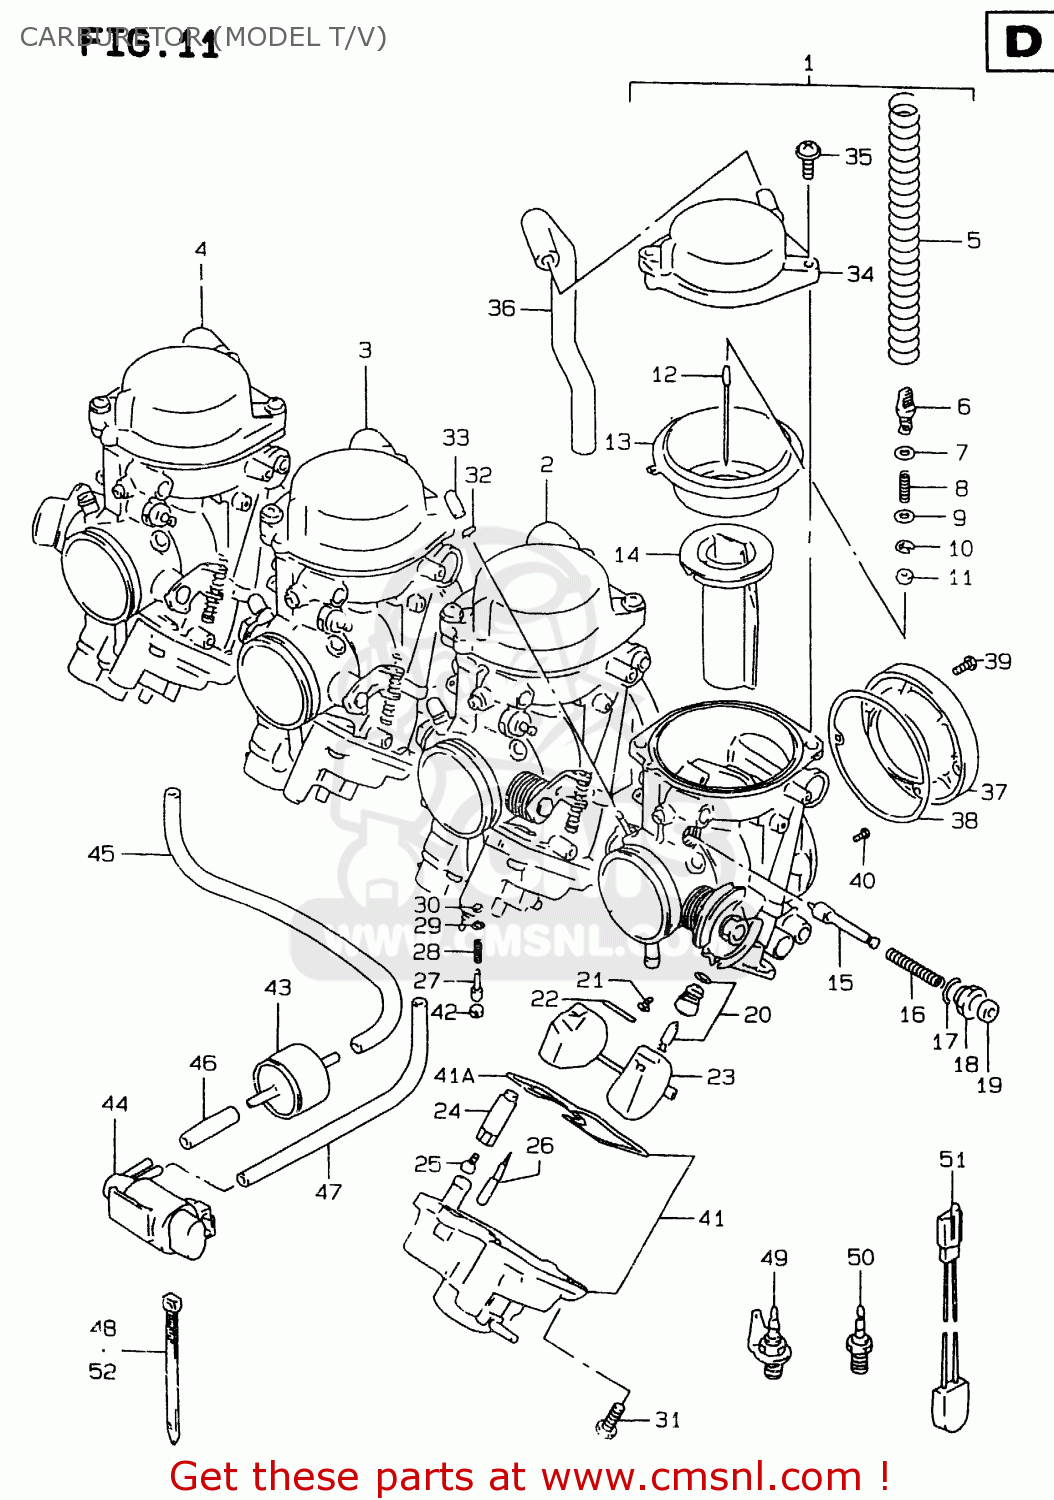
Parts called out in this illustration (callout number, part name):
1	CARBURETOR ASSY, LH
2	CARBURETOR ASSY, ML
3	CARBURETOR ASSY, MR
4	CARBURETOR ASSY, RH
5	SPRING
6	HOLDER
7	O RING(D:1.9,ID:4.8)
8	SPRING
9	WASHER
10	E RING,MULTIPLE JET NOZZLE
11	RING
12	JET,NEEDLE(6E38-54)
13	DIAPHRAGM
14	VALVE,PISTON
15	PLUNGER
16	SPRING
17	O RING
18	GUIDE SCREW,PLUNGER
19	CAP,STARTER VALVE
20	VALVE ASSEMBLY,NEEDLE
21	SCREW
22	PIN,FLOAT
23	FLOAT ASSY
24	HOLDER,JET
25	JET,MAIN(125)
26	JET,PILOT(12.5)
27	ADJUSTER
28	SPRING,THROTTLE SCREW
29	WASHER
30	O RING,PILOT AIR SCREW
31	SCREW
32	CLIP
33	CAP
34	COVER ASSY
35	SCREW
36	HOSE
37	FUNNEL
38	GASKET
39	SCREW
40	JET,PILOT(127.5)
41	BODY ASSEMBLY,FLOAT,LEFT
41A	O RING
42	PLUG
43	VALVE,VACUUM TRANSMITTING
44	VALVE ASSY,3WAY SOLENOID
45	HOSE(4X8X600)
46	HOSE(4X8X600)
47	HOSE(4X8X600)
48	CLAMP(L:95)
49	HEATER ASSY,CARBURETOR(15W)
50	HEATER, CARB.
51	THERMO SWITCH,CARB HEATER
52	CLAMP(L:95)
